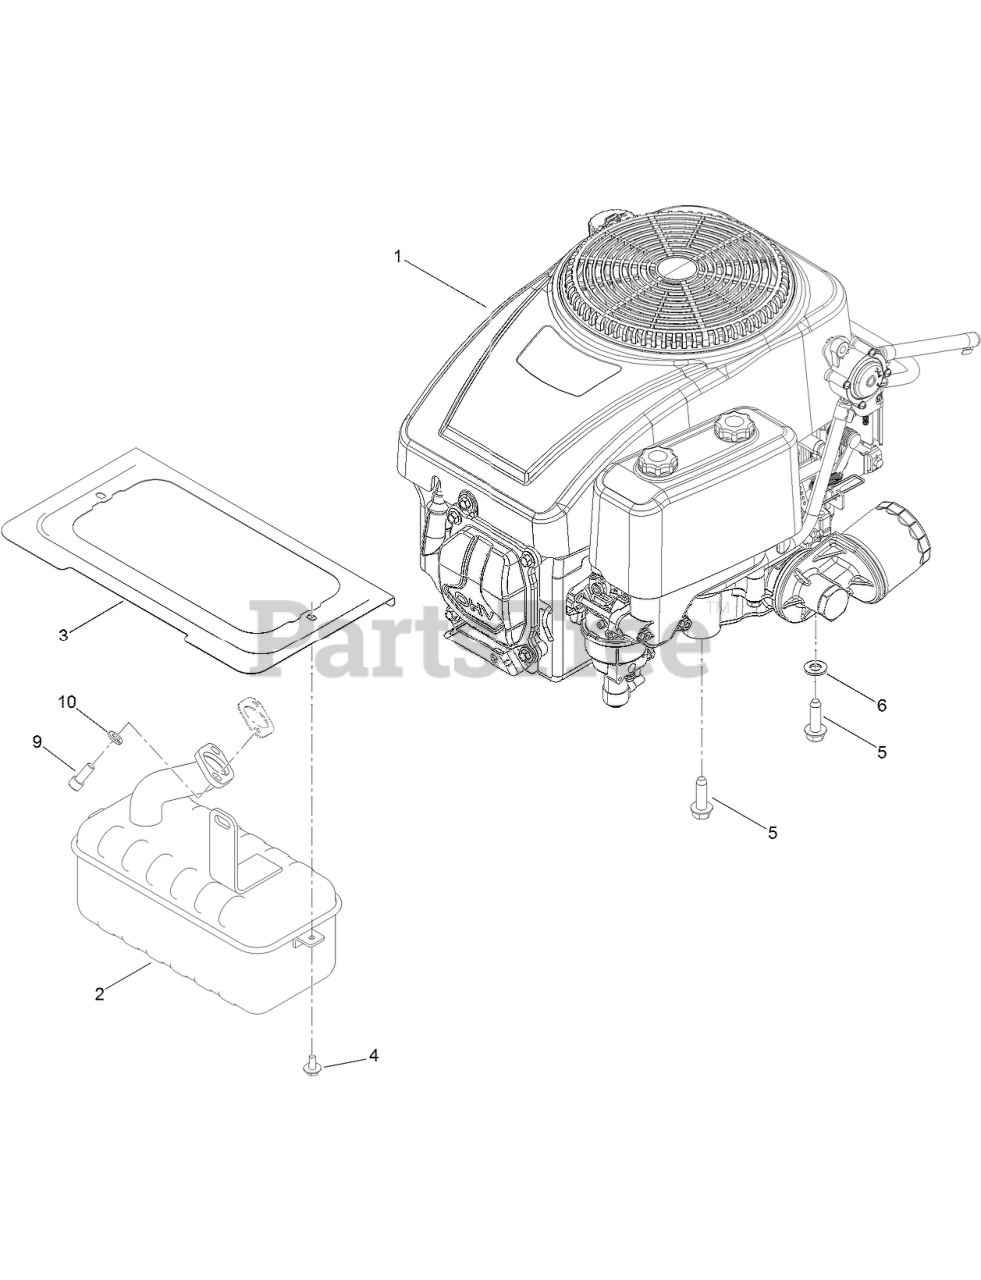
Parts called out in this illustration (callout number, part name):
1	ENGINE-1P92F-1
2	MUFFLER
3	SHIELD-HEAT
4	SCREW-HHFTF
5	SCREW-TAPTITE
6	WASHER-FLAT
9	SCREW-HSH
10	WASHER-LOCK
